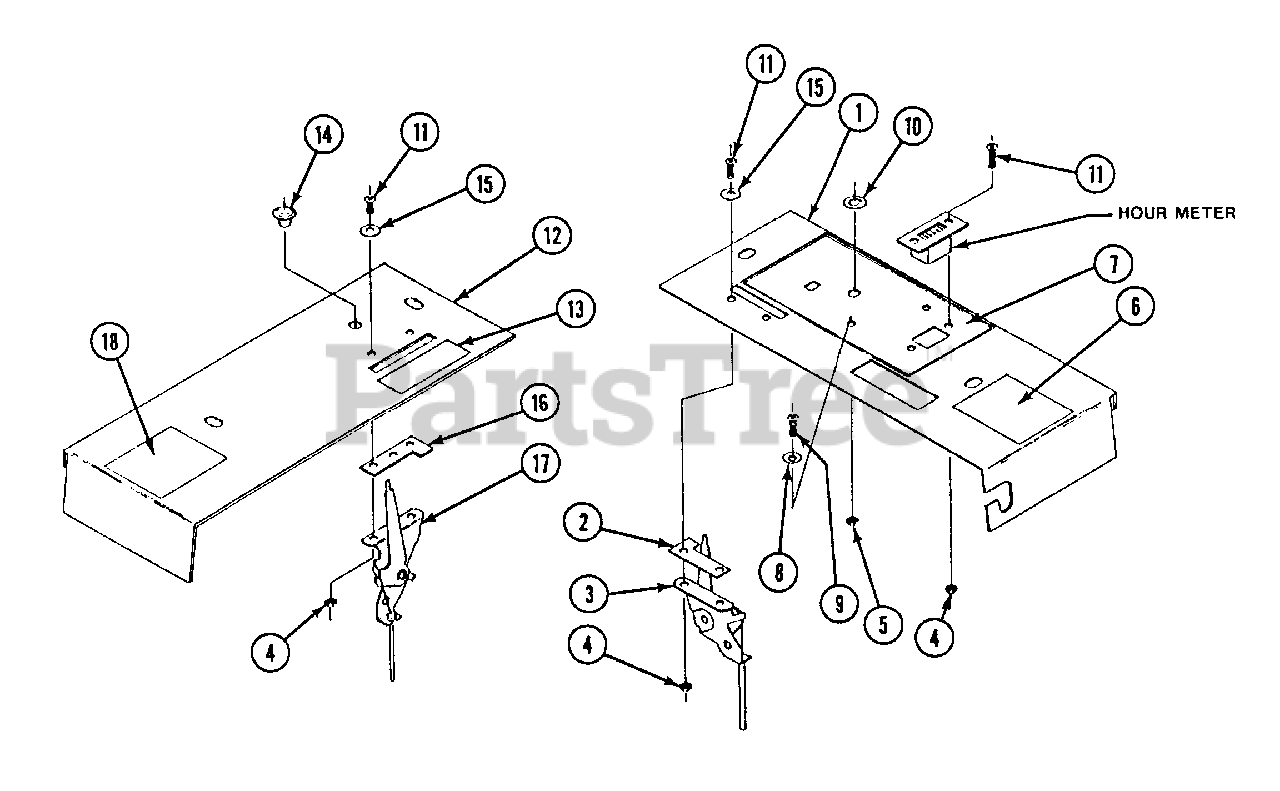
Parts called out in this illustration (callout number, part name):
1	FENDER CAP, RH (RED)
2	THROTTLE STOP PLATE
3	THROTTLE CABLE
4	LOCKNUT, NYLOCK: 6-32
5	LOCKNUT, NYLOCK: 8-32
6	DECAL,"CAUTION TO AVOID"
7	HOUR METER
8	DECAL, INST. PANEL
9	FLATWASHER; NO.8
10	SCREW, MACHINE: 8-32 X 3/4
11	D-WASHER
12	SCREW, MACHINE: 6-32 X 5/8
13	FENDER CAP, LH (RED)
14	DECAL,"CHOKE"
15	PLASTIC PLUG
16	FLAT WASHER: NO.6
17	CHOKE STOP PLATE
18	CHOKE CABLE
